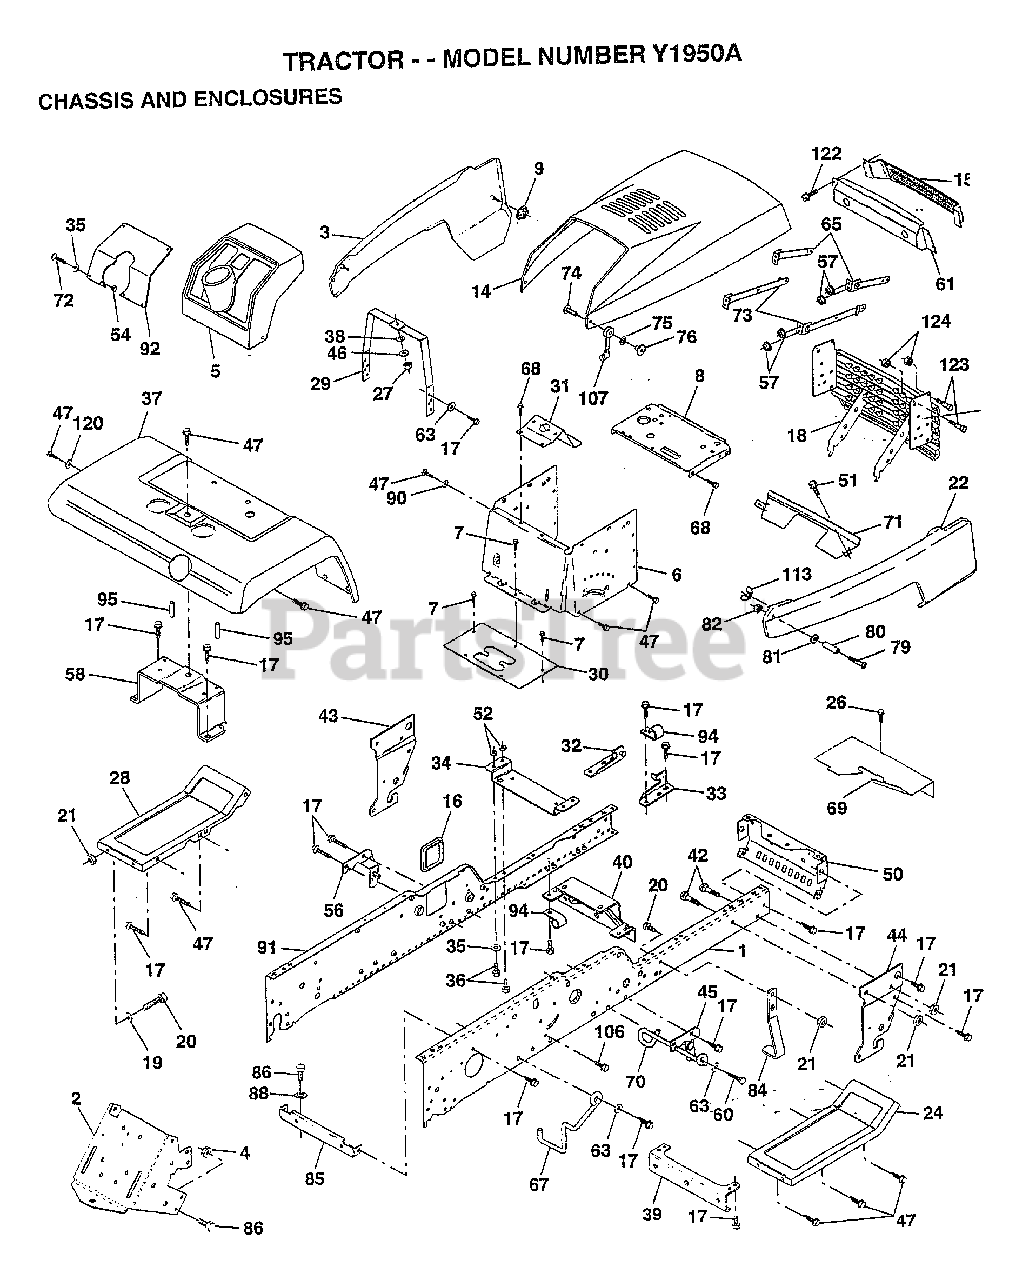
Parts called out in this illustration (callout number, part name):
2	DRAWBAR GT
4	NUT.7/16
5	DASHBOARD BLACK
6	DASH.1PC.LOWER
7	SCREW
8	SUPPORT.DASH.BTRY
9	PAL NUT LT
15	LENS.BAR.CLEAR
16	COVER ACCESS
17	SCREW
19	WASHER
20	BOLT
22	PANEL SIDE RH
24	FOOTREST.RH.LT/GT
26	SCREW
28	FOOTREST.LH.LT/GT
29	DASH.SUPT.YP/HUSQ
30	SADDLE.SCR.6SP
31	BRAKET.SUPT.STEER
32	BRACKET ASM FRAME
33	BRACKET ASM FRAME
34	BRACKET.ENG.SUPT.
35	WASHER
36	BOLT
37	FENDER
38	WASHER PM
39	BRACKET.AXLE.FRT.
43	BRACKET.SUS.FT.LH
44	BRACKET.SUS.FT.RH
46	LOCKWASHER
47	SCREW LT
50	BRACKET.CHASSIS.
51	SCREW CRT
57	NUT HXKEP 1/4X20
58	BRKT.ASM.FENDER
60	SCREW
63	WASHER
67	GUIDE BELT TRANS
68	SCREW LT
69	SHIELD.HEAT.MUF
70	GUIDE.BELT.MID.SP
71	STRAP.GRILLE.PNT.
72	SCREW
74	SCREW
75	LOCKWASHER
76	WELDNUT
79	SCREW
80	SPACER LT
81	WASHER
84	STOP.OVER.CENTER
85	BRACKET.SUPT.TRAN
86	BOLT
88	LOCKWASHER
90	LOCKWASHER
92	PLATE SLKSCR YP
94	CLIP GTV
95	NUT-PUSH YT
107	HOOD LATCH T
120	WASHER HYT
124	NUT
